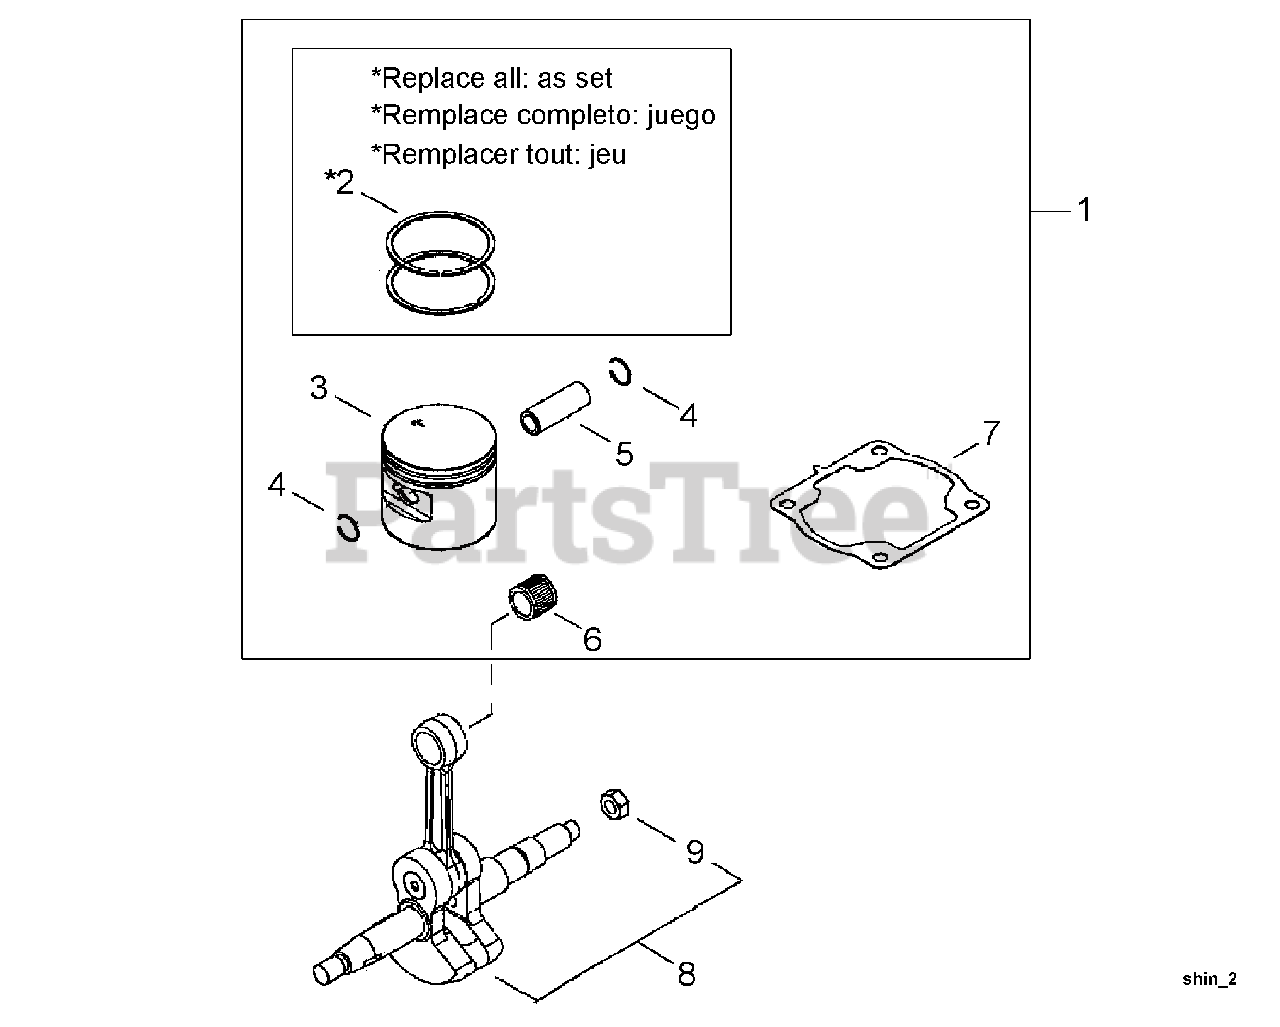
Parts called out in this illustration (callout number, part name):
1	PISTON KIT
2	RING, PISTON
4	RING, RETAINING
5	PIN, PISTON
6	BEARING, NEEDLE
7	GASKET, CYLINDER
8	CRANKSHAFT ASSY
9	NUT - 10
